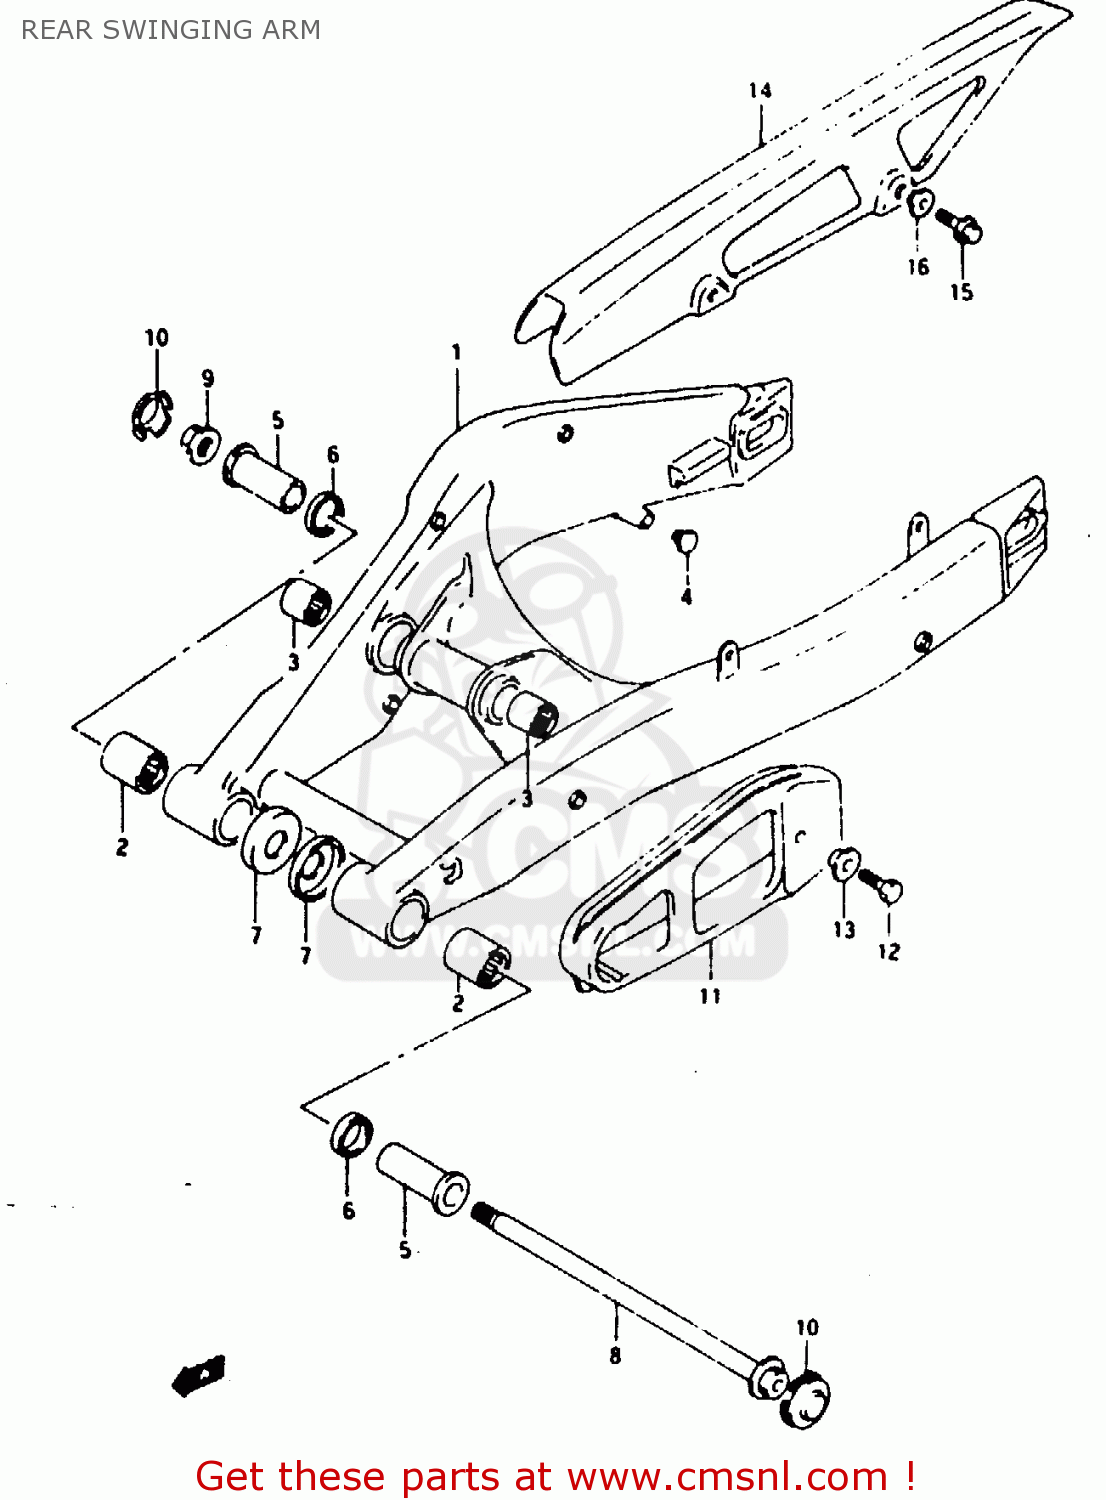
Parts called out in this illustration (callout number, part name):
1	SWINGING ARM ASSY, REAR (SILVER)
2	BEARING(20X27X30)
3	BEARING(17X24X25)
4	CAP(OD:12)
5	SPACER,RR SWGARM PIVOT OUTER
6	OIL SEAL
7	COVER, PIVOT DUST
8	SHAFT, PIVOT
9	NUT
10	CAP,CUSHION LEVER
11	BUFFER,CHAIN TOUCH DEFENSE
12	BOLT
13	WASHER
14	CASE,CHAIN
15	BOLT
16	WASHER
